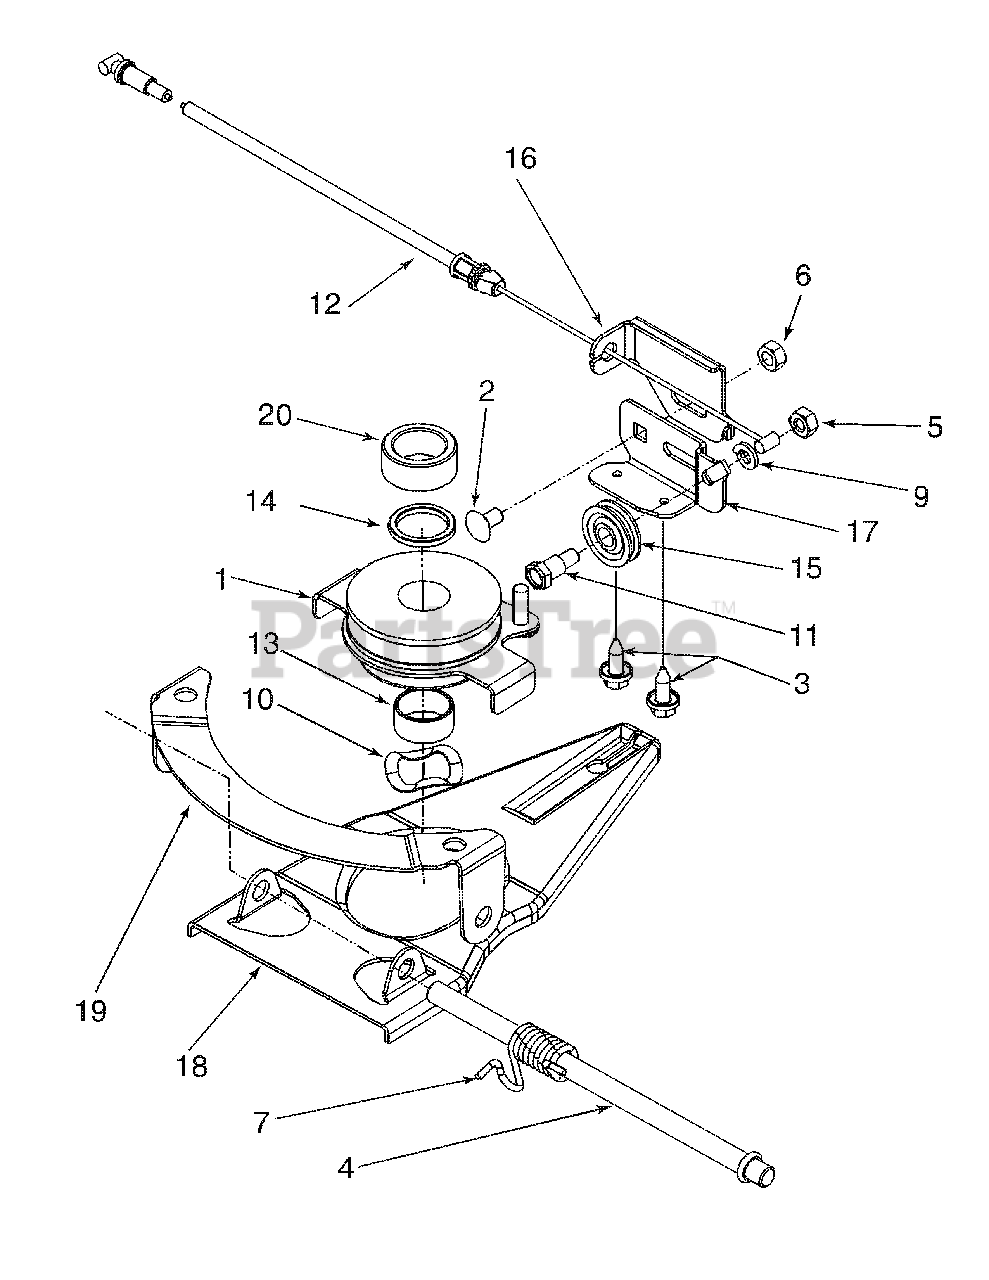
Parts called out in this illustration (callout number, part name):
1	Multi Speed Pulley Ass’y
2	Carriage Bolt 1/4-20 x .62\5" Lg. Gr. 2
3	Hex Wash HD. TT Tap Scr. 1/4-20 x .62
5	Hex Nut 1/4-28
6	Flanged Lock Nut 1/4-20 Gr. F Nylon
7	Torsion Spring LH
9	L-Wash 1/4 ID
10	Wave Washer .88 ID x 1.38 OD x .029
11	Hex Shld.Scr.1/4-28 x .375
12	Pulley Cable 53" Lg.
13	Sleeve Spacer .88 ID x 1.0 OD x .48
14	Sleeve Spacer .88 ID x 1.13 OD x .12
15	Cable Guide Roller
16	Cable Adjustment Bracket
17	Cable Mounting Bracket
20	Sleeve Spacer .878 x 1.25 x .545 (with Honda engine only)
